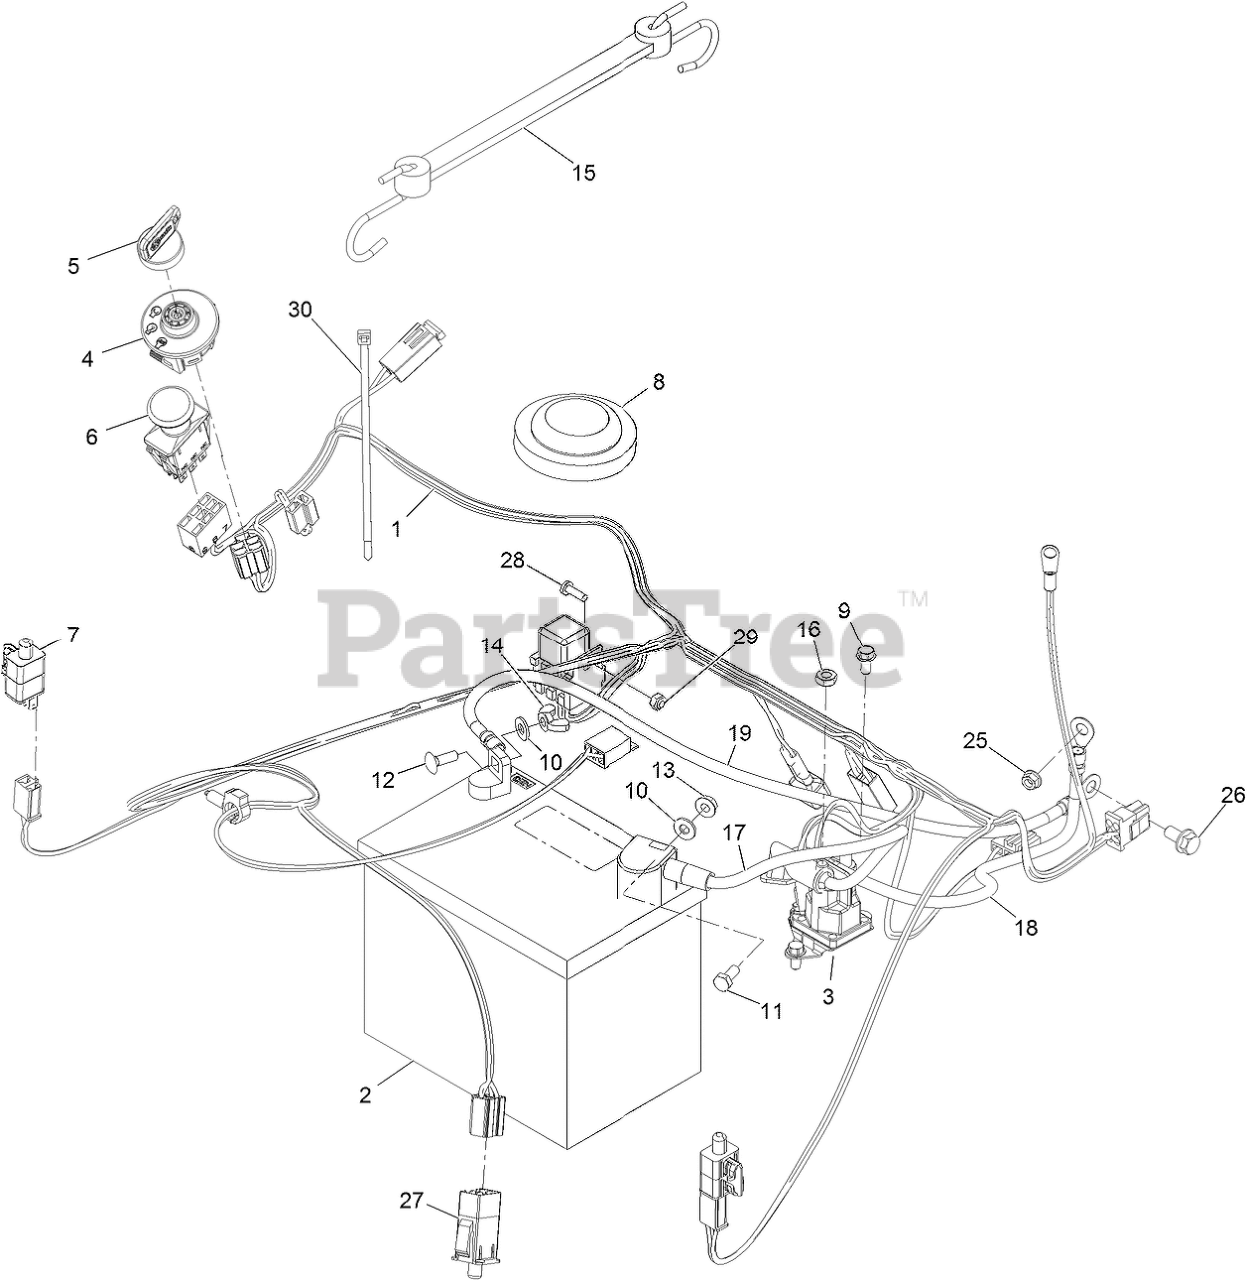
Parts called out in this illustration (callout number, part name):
1	Harness-Wire,
2	BATTERY
3	SOLENOID
4	SWITCH-IGNITION
5	KEY-IGNITION
6	SWITCH-PTO
8	SWITCH-SEAT
9	SCREW-HWH
10	Washer-Flat
11	SCREW-HH
12	BOLT-CARR
14	NUT-WING
15	HOLDDOWN-BATTERY
17	CABLE-BATTERY, RED
18	CABLE-BATTERY, POSITIVE
19	CABLE-BATTERY, BLACK
26	SCREW-HHF
27	SWITCH-DELTA
28	SCREW-PPH
29	NUT-LOCK, NI
30	TIE-CABLE
